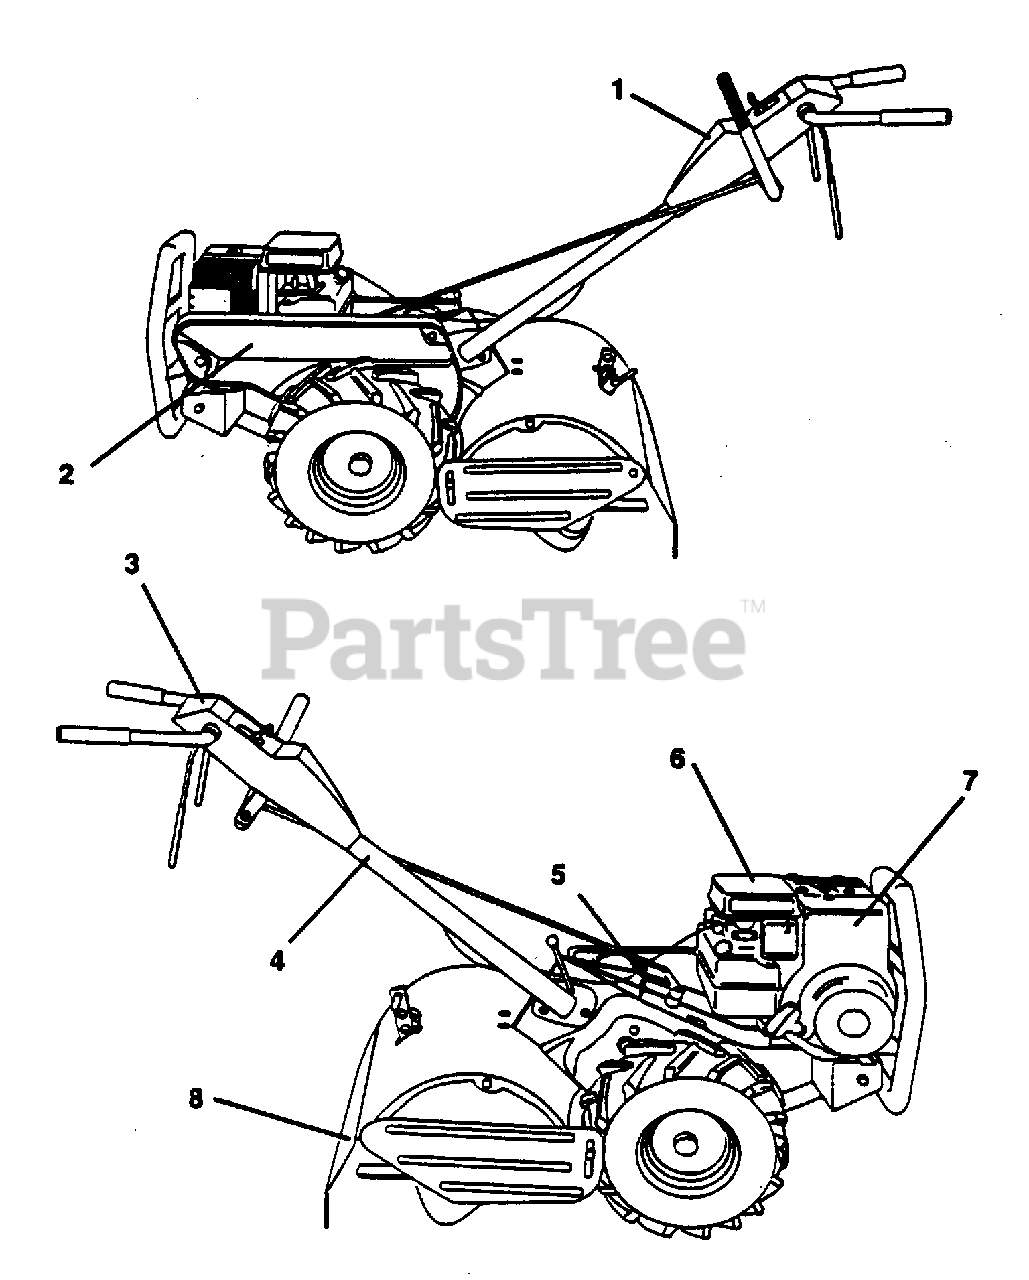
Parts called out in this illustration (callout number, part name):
1	Decal, Logo
2	Decal, Logo
3	Decal, Instruction, Tilling (AYP part number)
4	Decal, Hand Placement (AYP part number)
5	Decal, Shift Indicator (AYP part number)
6	Decal, Caution (AYP part number)
7	Decal, Briggs & Stratton (AYP part number)
8	Decal, Warning, Rotating Tines (AYP part number)
